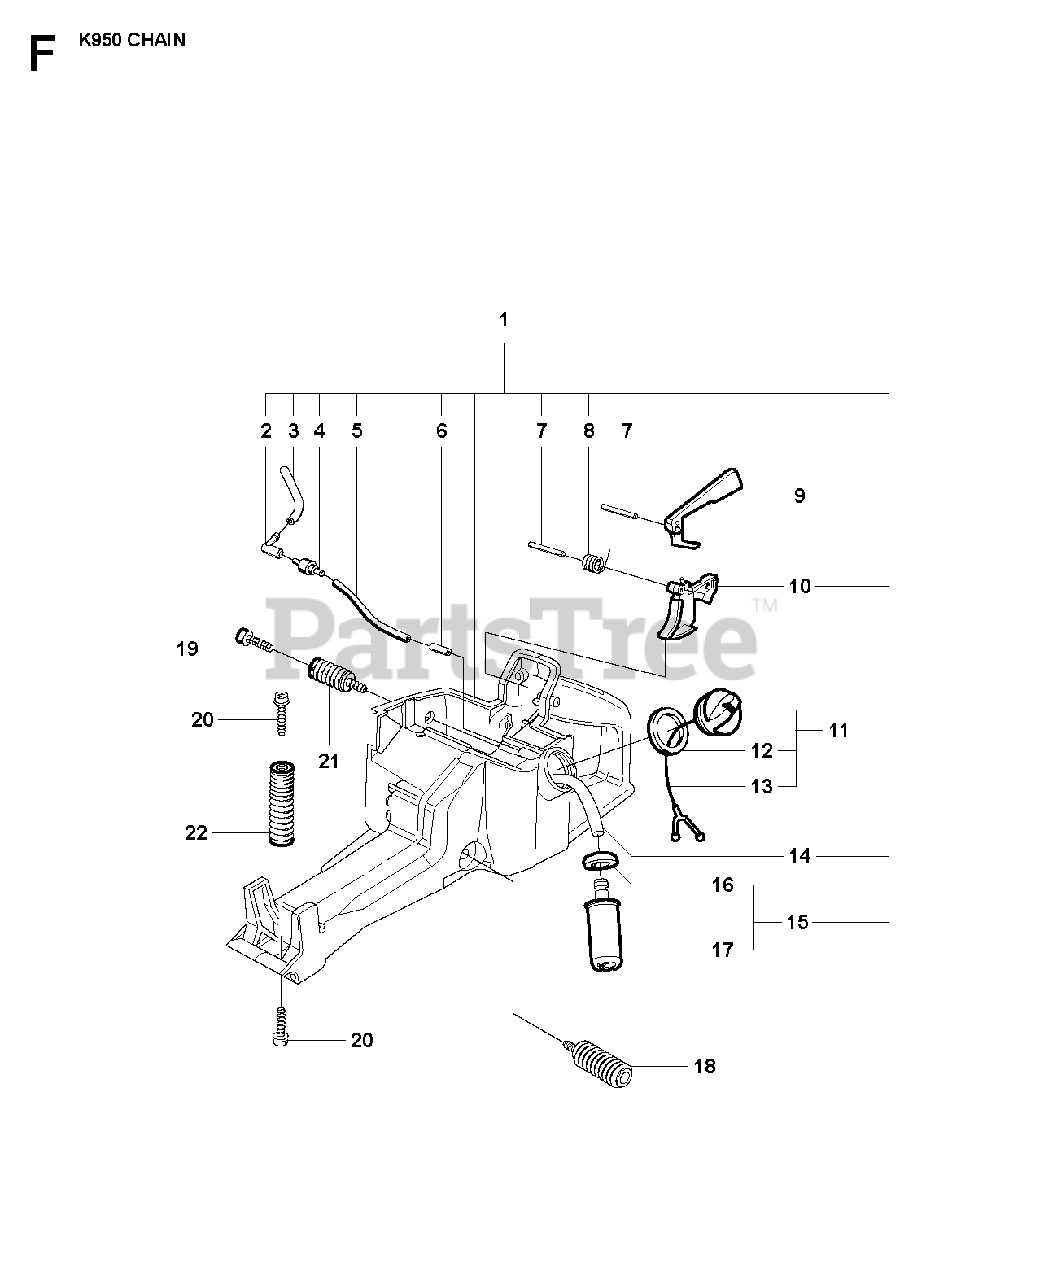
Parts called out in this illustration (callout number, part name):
1	FUEL TANKIncl. 2 - 11, 14, 15
2	CONNECTION BEND
3	FUEL HOSE
7	PARALLEL PIN
8	SPRING THROTTLE TRIG
9	THROTTLE LOCKOUT
11	TANK CAP ASSYIncl. 12, 13
14	FUEL HOSE
15	FUEL FILTERIncl. 16, 17
20	SCREW IHSCFM
21	ANTIVIBRATION ELEMENT
22	ANTIVIBRATION ELEMENT
